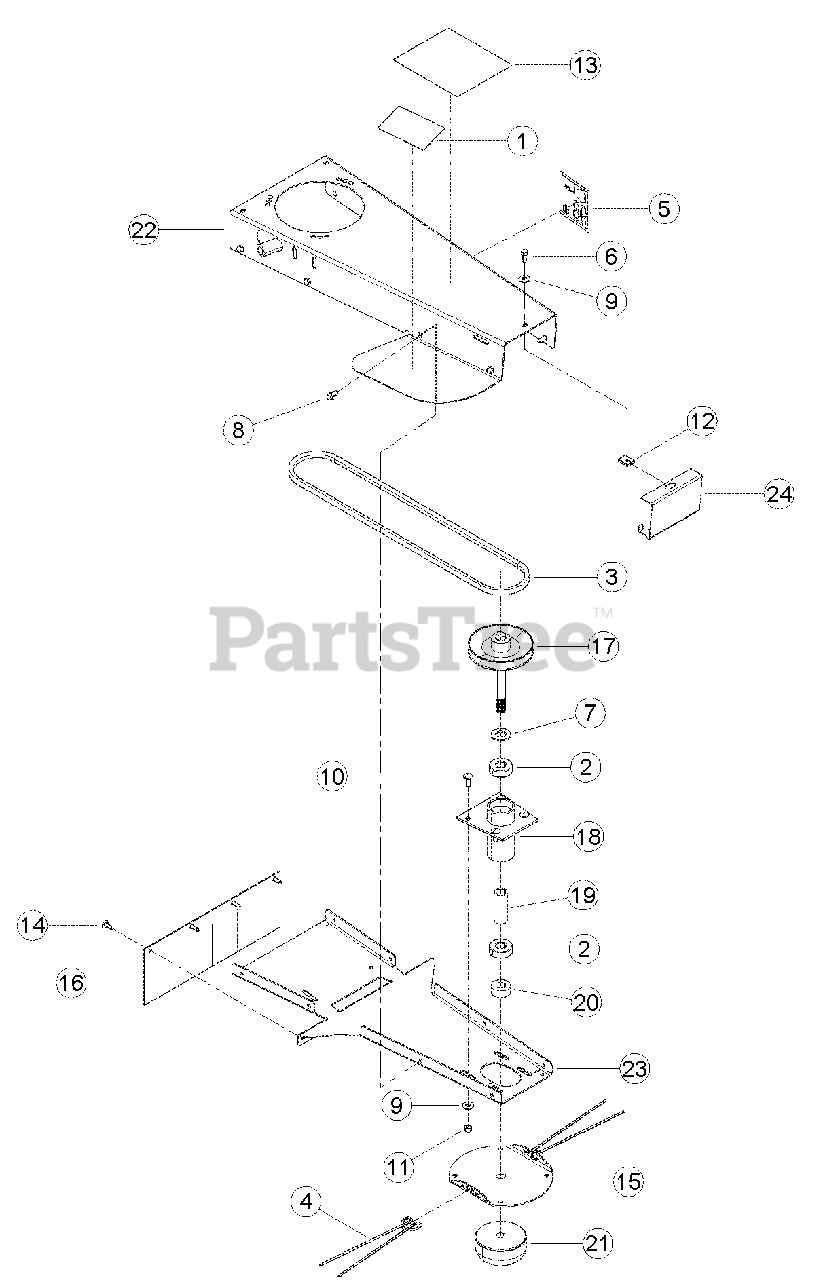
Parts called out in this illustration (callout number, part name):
1	DECAL, GRINDER DANGER
2	BEARING, 3/4 BALL
3	BELT, 4L 53 ARAMID
4	STRING, .155 X 20-1/2
5	DECAL, 98 DB (WT160TXS MODEL)
6	BOLT, 5/16 X 3/4 HEX HD GR5 ZP
7	WASHER, 3/4 SAE FLAT ZP
8	SCREW, 11/32 X 7/8 HWH AB THREAD ZP
9	WASHER, 5/16 FLAT ZP
10	BOLT, 5/16 X 7/8 CRG GR5 NC ZP
11	NUT, 5/16 NE NYLOCK ZP
12	NUT, 5/16-18 TINNERMAN U-TYPE
13	DECAL, MANUAL/SAFETY INFO
14	RIVET, PLASTIC 1/4 X 7/8
15	DISK, TRIMMER HEAD
16	FLAP, TRIMMER
17	WELDMENT, TRIMMER PULLEY
18	WELDMENT, SPINDLE HUB
19	SPACER, TRIMMER SPINDLE
20	SPACER, TRIMMER HEAD
21	WELDMENT, TRIMMER HEAD USE 72704-12
22	WELDMENT, TRIMMER BODY
23	BOTTOM, TRIMMER FRAME
24	COVER, FRONT TRIMMER
